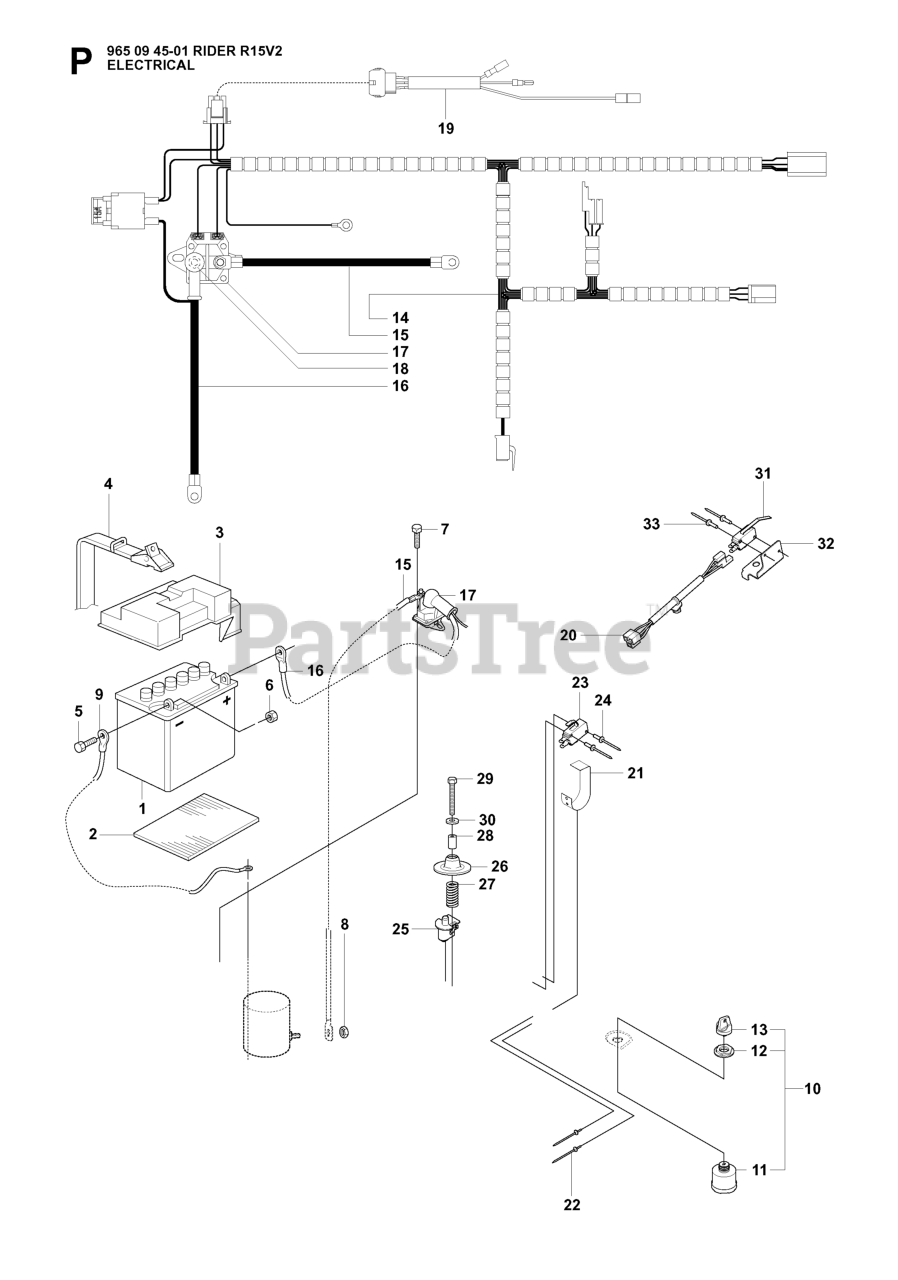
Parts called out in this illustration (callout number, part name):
1	BATTERY - DRY
10	IGNITION SWITCH
11	IGNITION SWITCH
13	IGNITION KEY
20	WIRING
23	%BRAKER
28	SPACER TUBE
29	SCREW
30	WASHER BRB 8.4X17
31	RP MICRO SWITCH
